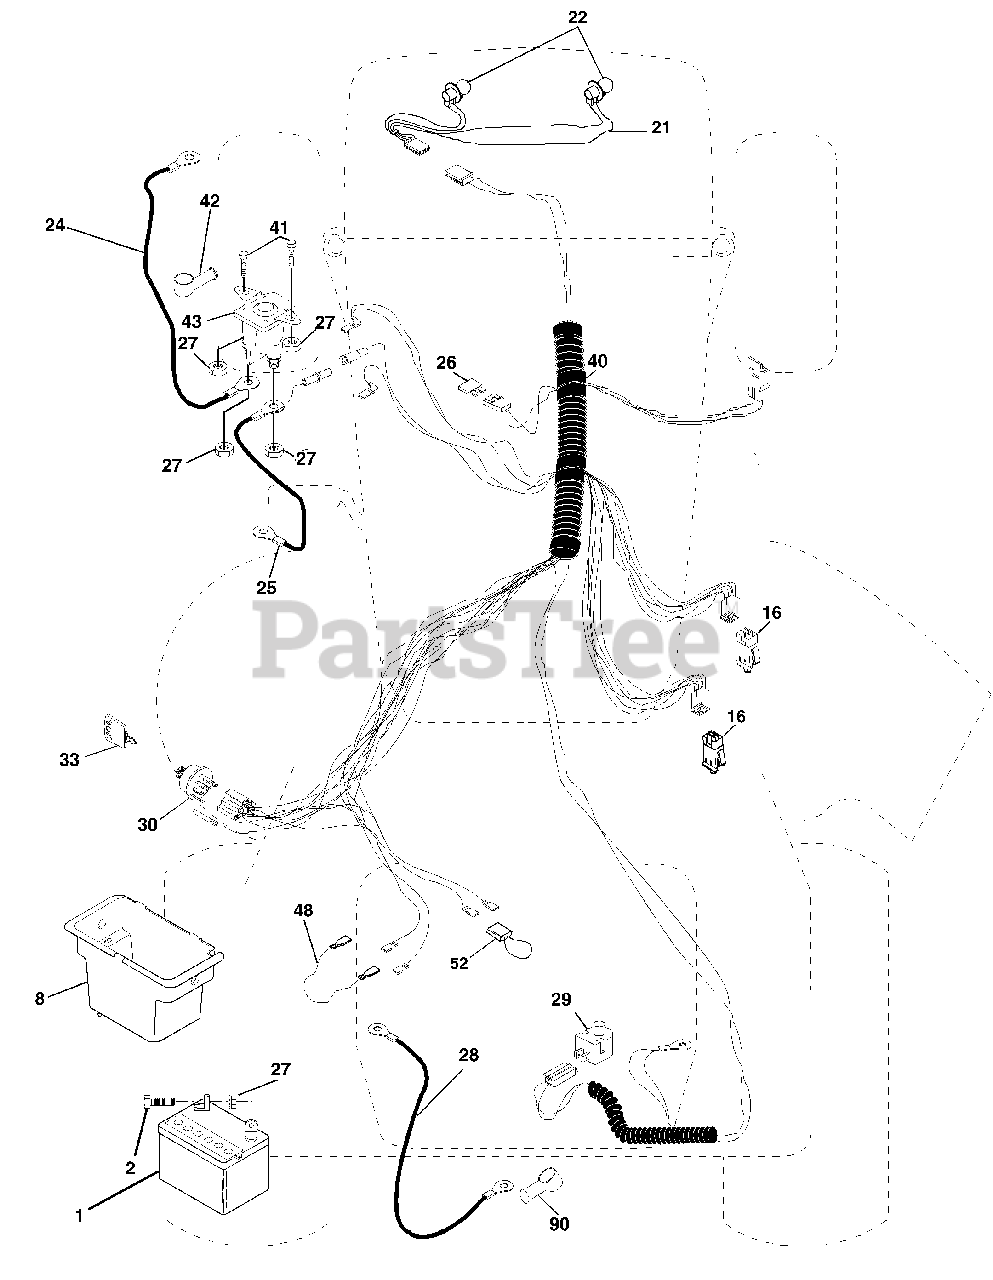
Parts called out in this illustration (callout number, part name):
1	Battery
2	Bolt Hex Hd 1/4-20unc X 3/4
8	Box Battery
16	Switch Interlock
21	Harness Asm Light W/4152j
22	Bulb Light #1156
24	Cable Battery 6 Ga 11" red
25	Cable Battery
26	Fuse 20 AMP
27	Nut Keps Hex 1/4-20 Unc
28	Cable Ground 6 Ga 12" black
29	Switch Plunger Nc Gray
30	Switch Ign
33	Key Ign
40	Harness Ign
41	Bolt Blk Fin Hex 1/4-20
42	Cover Terminal Red
43	Solenoid
48	Adapter Ammeter
52	Protection Wire Loop
90	Cover Terminal Battery
